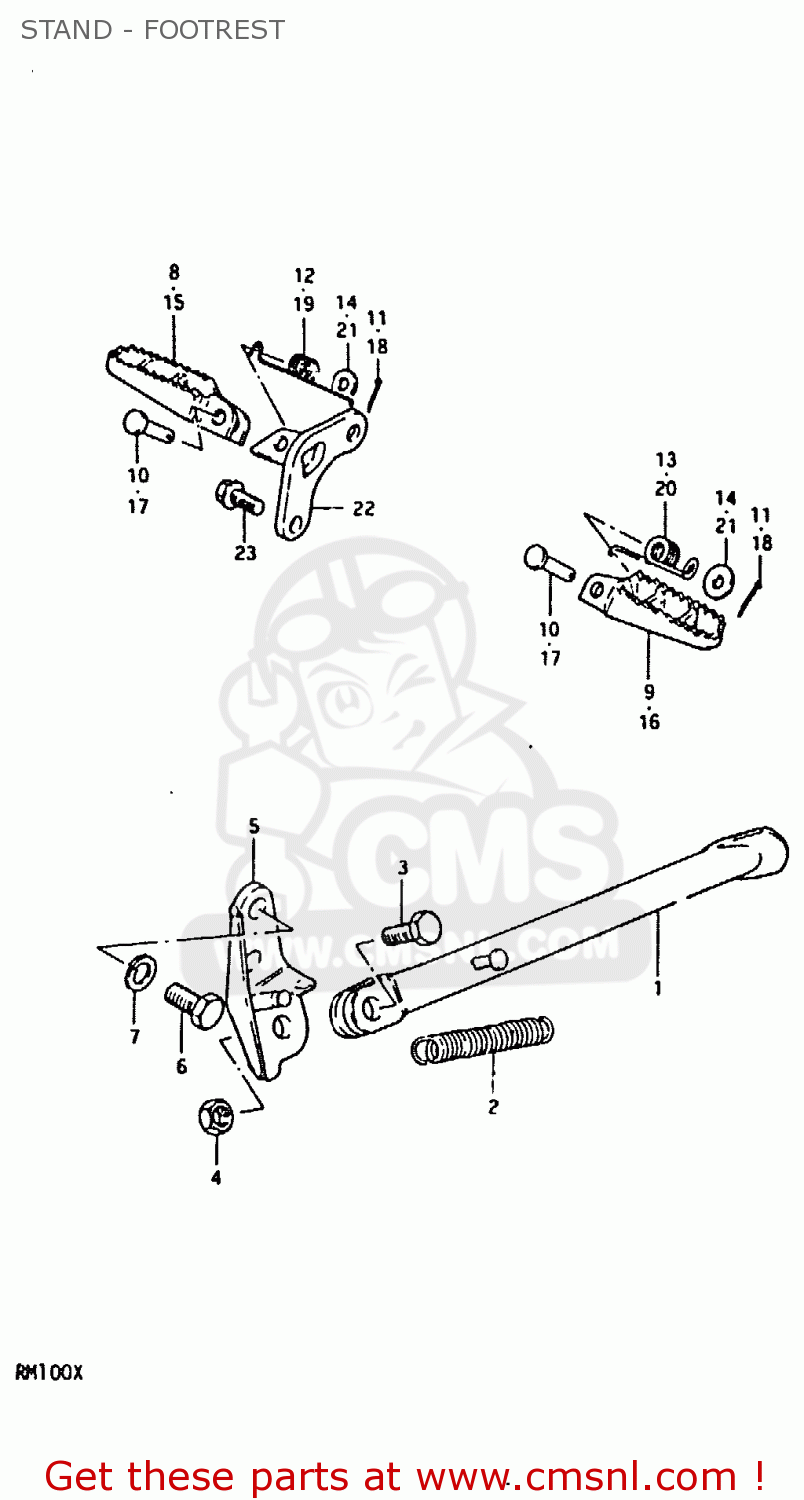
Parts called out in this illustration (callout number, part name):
1	STAND,SIDE
2	SPRING
3	BOLT(10X30)
4	NUT
5	BRACKET,PROP STAND
6	BOLT(10X19)
7	LOCK WASHER
8	RUBBER,FOOTREST
9	FOOTREST
10	PIN
11	PIN 20X20
12	SPRING
13	SPRING
14	WASHER
15	RUBBER,FRONT FOOTREST
16	FOOTREST
17	PIN
18	PIN 20X20
19	SPRING
20	SPRING
21	WASHER
22	HOLDER,FRONT FOOTREST,RIGHT
23	BOLT(10X20)
